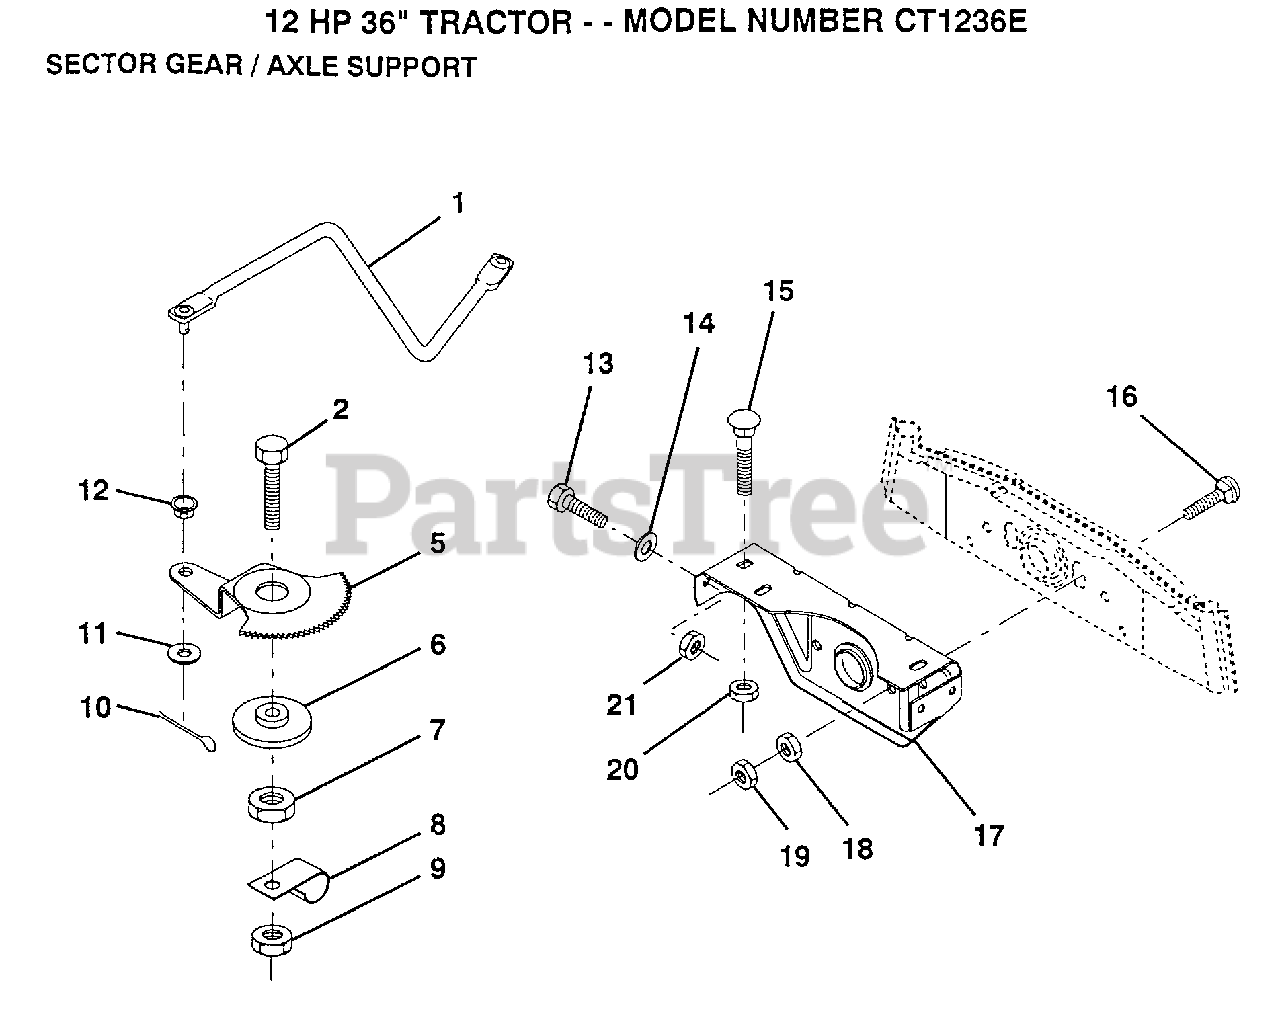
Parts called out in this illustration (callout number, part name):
1	DRAG LINK
2	"BOLT,HEX"
5	GEAR SECTOR
6	BUSHING
7	NUT
8	CLIP INSULATOR
9	NUT LTV
10	COTTER PIN
11	WASHER
12	BUSHING.DRAGLINK
13	BOLT
14	WASHER
15	BOLT
16	BOLT
17	"SUPT,FRT AXLE"
18	NUT.HEX.3/8-16UNC
19	LOCKNUT
